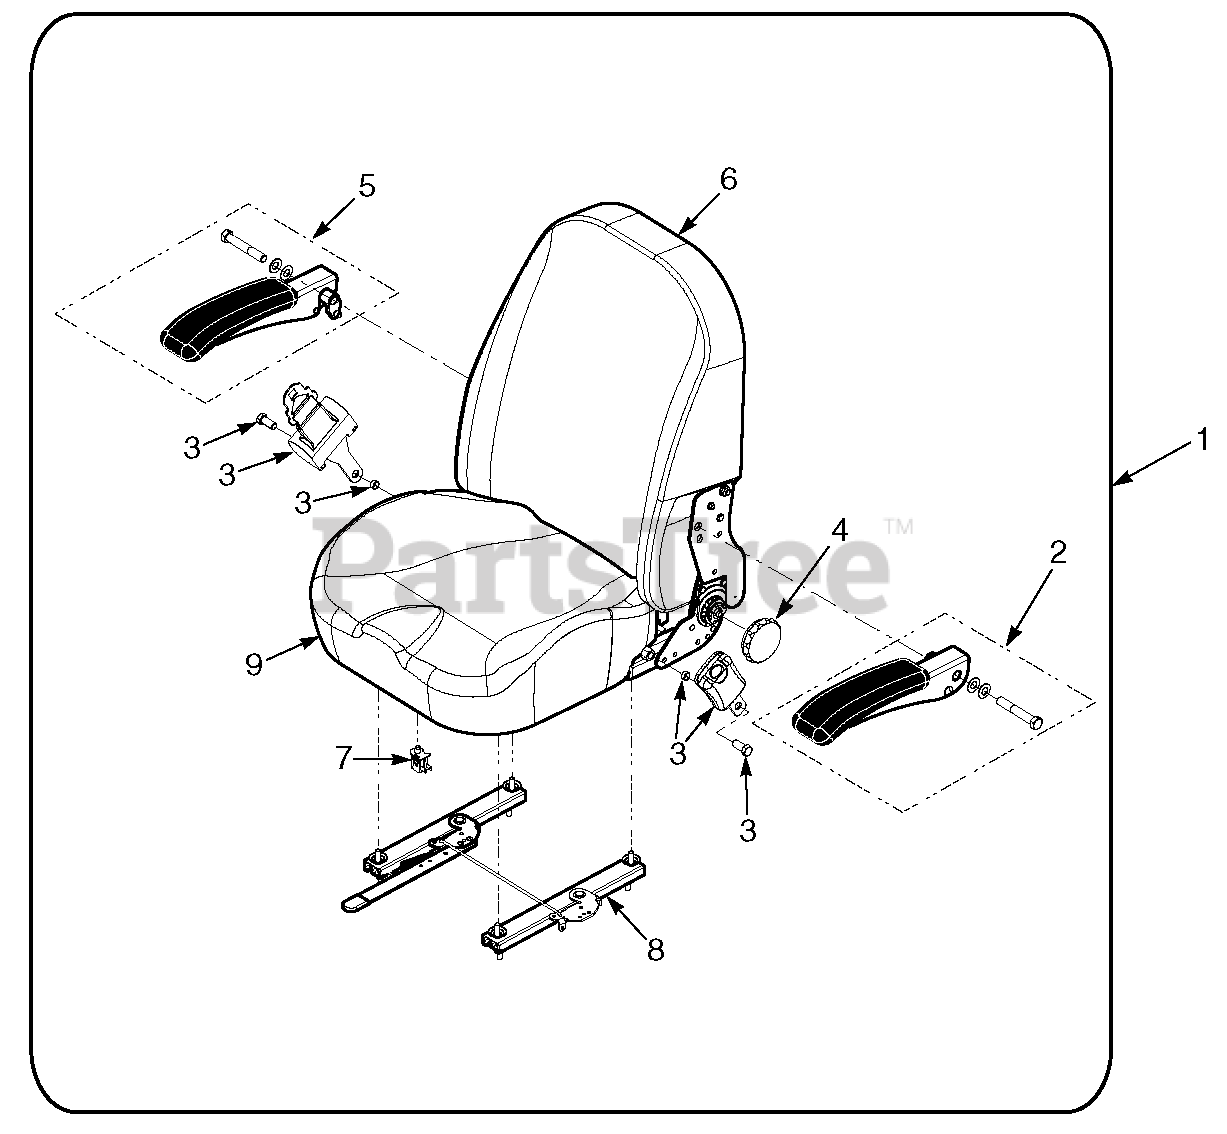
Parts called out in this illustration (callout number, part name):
1	Belt Cover, LH 61V
1	Belt Cover, RH 61V
2	Knob w/Stud
3	Nut, 5/8-11 UNC
4	Bolt, Hex Head 1/4-20 x 1"
5	Tapered Hub, 1.125" Bore
6	Pulley, 6.32" Dia.
8	Nut, Elastic Stop 3/8-16
9	Flatwasher, 3/8-.391 x .938 x .105
10	Dust Shield
11	Pulley, Idler
12	Belt, Deck Drive
13	Pulley, 5" Idler
14	Pulley, 3-1/2" Idler
15	Pulley, 6.32" Dia. Double Groove
16	Bearing
17	Idler Arm Assy.
18	Pivot, Idler
19	Bolt, Hex Head 3/8-16 x2-1/2"
20	Bolt, Hex Head 7/16-14 x 1"
21	Lockwasher, 7/16" Spring
22	Boss, Spring Anchor
23	Idler Arm Assy.
24	Bolt, Hex Head 3/8-16 x 3"
25	Spring, LH Cutter Deck
26	Guide Roller
27	Shaft Weldment
29	Nut, Serrated Flange 3/8-16
30	Spring Mount, SCZ
31	Bolt, Hex Head 3/8-16 x1-1/2"
32	Pusharm Assy., LH
32	Pusharm Assy., RH
33	Rod Weldment, Pusharm
34	Bolt, Hex Head 5/16-18 x 1"
35	Nut, Elastic Stop 5/16-18
36	Bolt, Hex Head 3/8-16 x 1"
37	Cutter Deck w/Decals
38	Wear Pad
39	Spindle Assembly
40	Nut, Center Lock 5/16-18
41	Flatwasher, 5/16-.344 x .688 x .065
42	Bolt, Carriage 5/16-18 x 3/4"
43	Shaft, Spindle
44	Seal, Top
45	Bearing Assembly
46	Grease Fitting
47	Relief Fitting, Spindle
48	Spindle Housing
49	Spacer, Outside
50	Spacer, Inside
51	Seal, Bottom
52	Spindle Bushing
53	Nut, Special 1-1/16 - 18
54	Bolt, Hex Head 5/8-11 x 9-1/2"
55	Flatwasher, 5/8-.688 x 1.75 x .134 HD
56	Cutter Blade, 21"
57	Spacer, Spindle Bottom
58	Bolt, Hex Head 5/16-18 x1-3/4"
59	Key, 1/4 x 1/4 x 2"
60	Shaft Weldment
61	Wheel, Anti-Scalp
62	Baffle, Flange - 61V
63	Bolt, Carriage 3/8-16 x 1"
64	Baffle, Turbo - 61V
65	Wheel, Anti-Scalp
66	Bushing, .376 ID Oilite
67	Bracket, Anti-Scalp Wheel
68	Bolt, Carriage 3/8-16 x 4"
69	Nut, Center Lock 3/8-16
70	Bolt, Hex Head 3/8-16 x 1"Serrated Flange
71	Nut, Elastic Stop 7/16-14
72	Flatwasher, 1/2-.531 x 1.062x .095
73	Lever Assembly, Deck Level
74	Bolt, Deck Adjust
75	Bolt, Carriage 7/16-14 x1-1/4"
76	Bolt, Hex Head 3/8-16 x 3"
77	Bolt, Hex Head 3/8-16 x 2-1/4"
78	Deck Spring
79	Spacer
80	Bolt, Hex Head 5/16-18 x1-3/4"
81	U-Nut, 3/8-16
82	Discharge Chute Assy. 61V
83	Bolt, Hex Head 5/16-18 x 4-1/2"
84	Spring, Discharge Chute
85	Cap, Spindle
